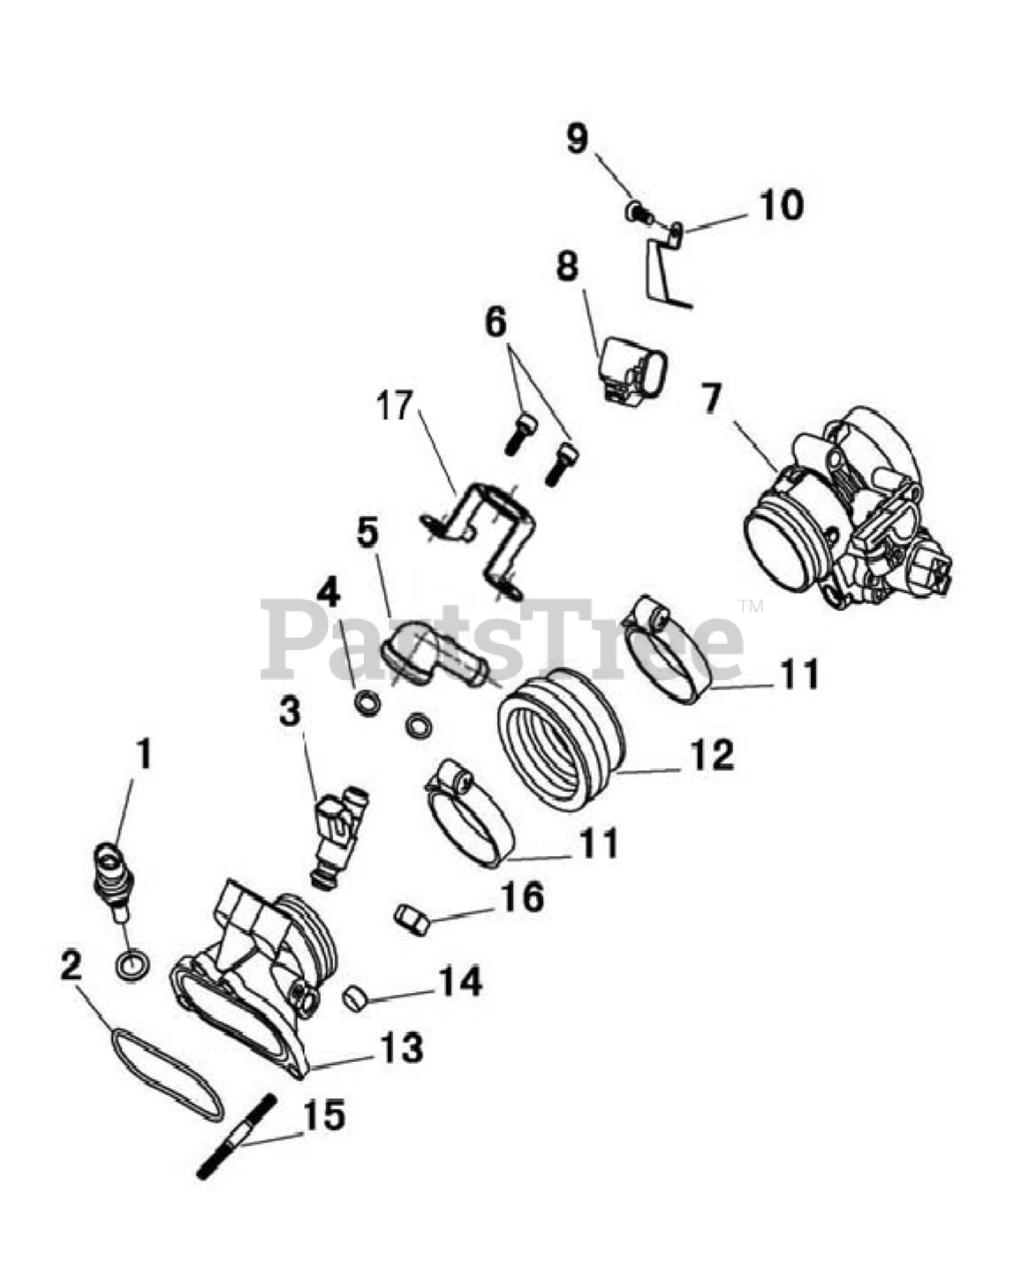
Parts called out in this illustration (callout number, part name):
1	Water Temperature Sensor
2	Seal,intake-tube
3	Fuel Injector?25377439?
4	Aluminum Washer 6x12x1.5
5	FUEL INJECTOR FIxED SEAT
6	HExAGON SOCKET HEAD CAP SCREW M6 x 12
7	THROTTLE BODY ASSEMBLY
8	Temperature/Pressure Sensor
9	Cross recessed pan head screw, single coil spring lock washer assemblies M4x8
10	Press Plate,TMAP
11	Hose Clamp Assy 50?70
12	INLET PIPE JOINT
13	Intake-tube Assy
14	Bushing 7x9x8
15	Stud M6x32
16	Hexagon Flange Nut M6
17	FUEL INJECTOR CLAMP
